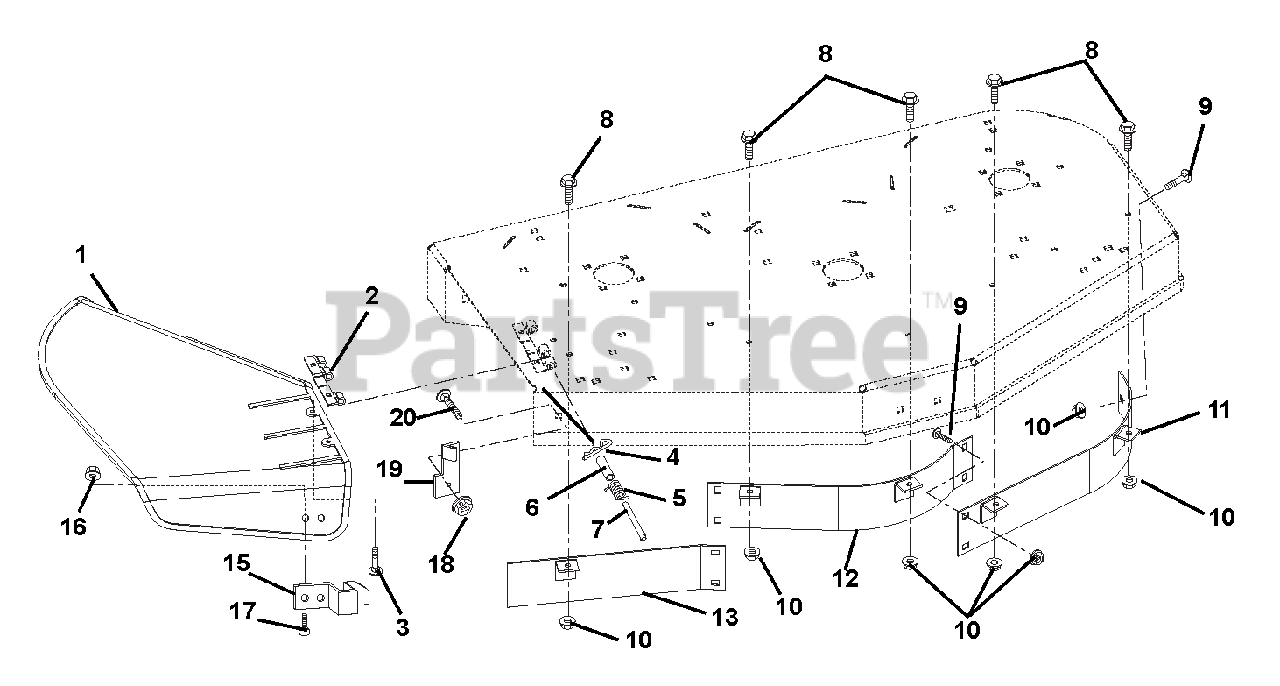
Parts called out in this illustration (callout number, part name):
1	DEFLECTOR, CHUTE
2	HINGE PLATE
3	@BLT-RDHDSQNK .25-20X.75 G5YZ
4	PIN-HAIR INT .08X.18X1.18 YWZC
5	SG-TORS .095X.50X 1.0
6	BSHG-SLV .334 X .502 X 1.437
7	PIN, 5/16 X 5.80"
8	BLT-SERHFWH .312-18X.75 YWZC
9	@BLT-RHDSSQNK .31-18X.62 G5YZ
10	@NUT-LK-NYL-FLG .31-18 YWZC
11	BAFFLE - LEFT FRONT - 40"
12	BAFFLE - CENTER FRONT - 40"
13	BAFFLE - RIGHT FRONT - 40"
14	DEFLECTOR-40"
15	FLAT SPRING
16	@NUT-LK-TOP-FLG .25-20 YWZC
17	@BLT-RDHDSQNK .25-20X.50 G5YZ
18	@NUT-LK-NYL-FLG .38-16 YWZC
19	BRACKET, CHUTE LOCK
20	@BLT-RDHDSQNK .38-16X1.50 G5YZ
